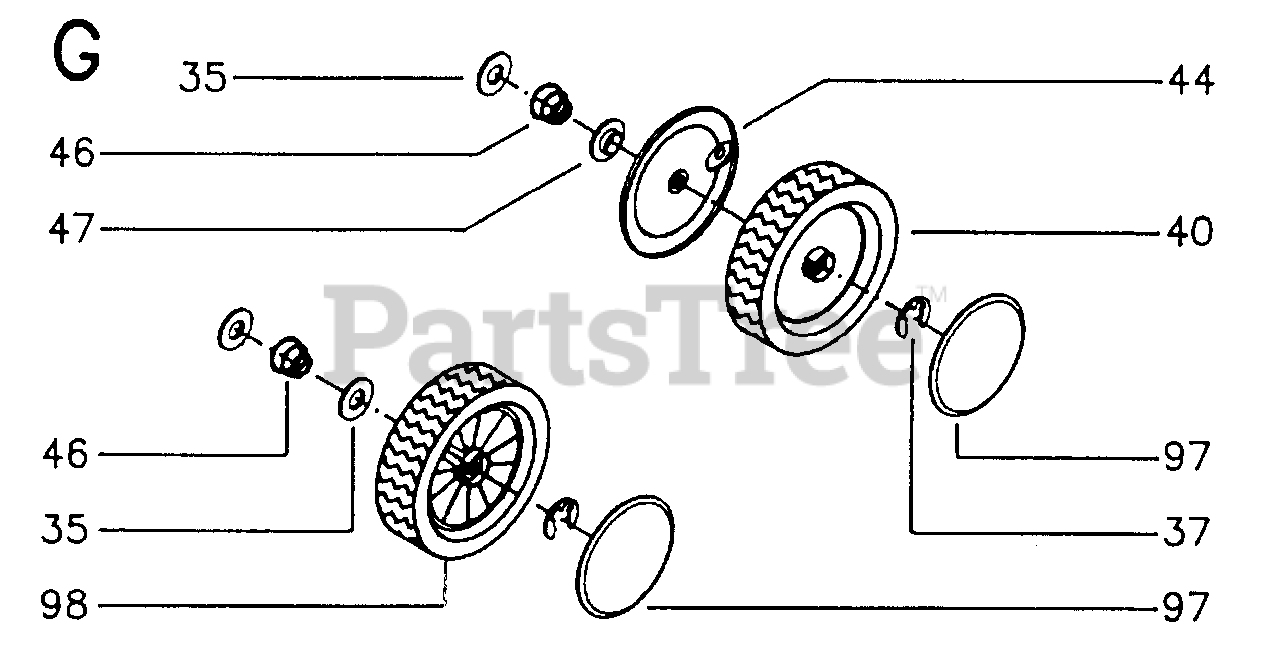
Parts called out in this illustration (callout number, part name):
40	REAR WHEEL R48
44	WHEEL RIM TIGHTENING
46	CONE SPRING
